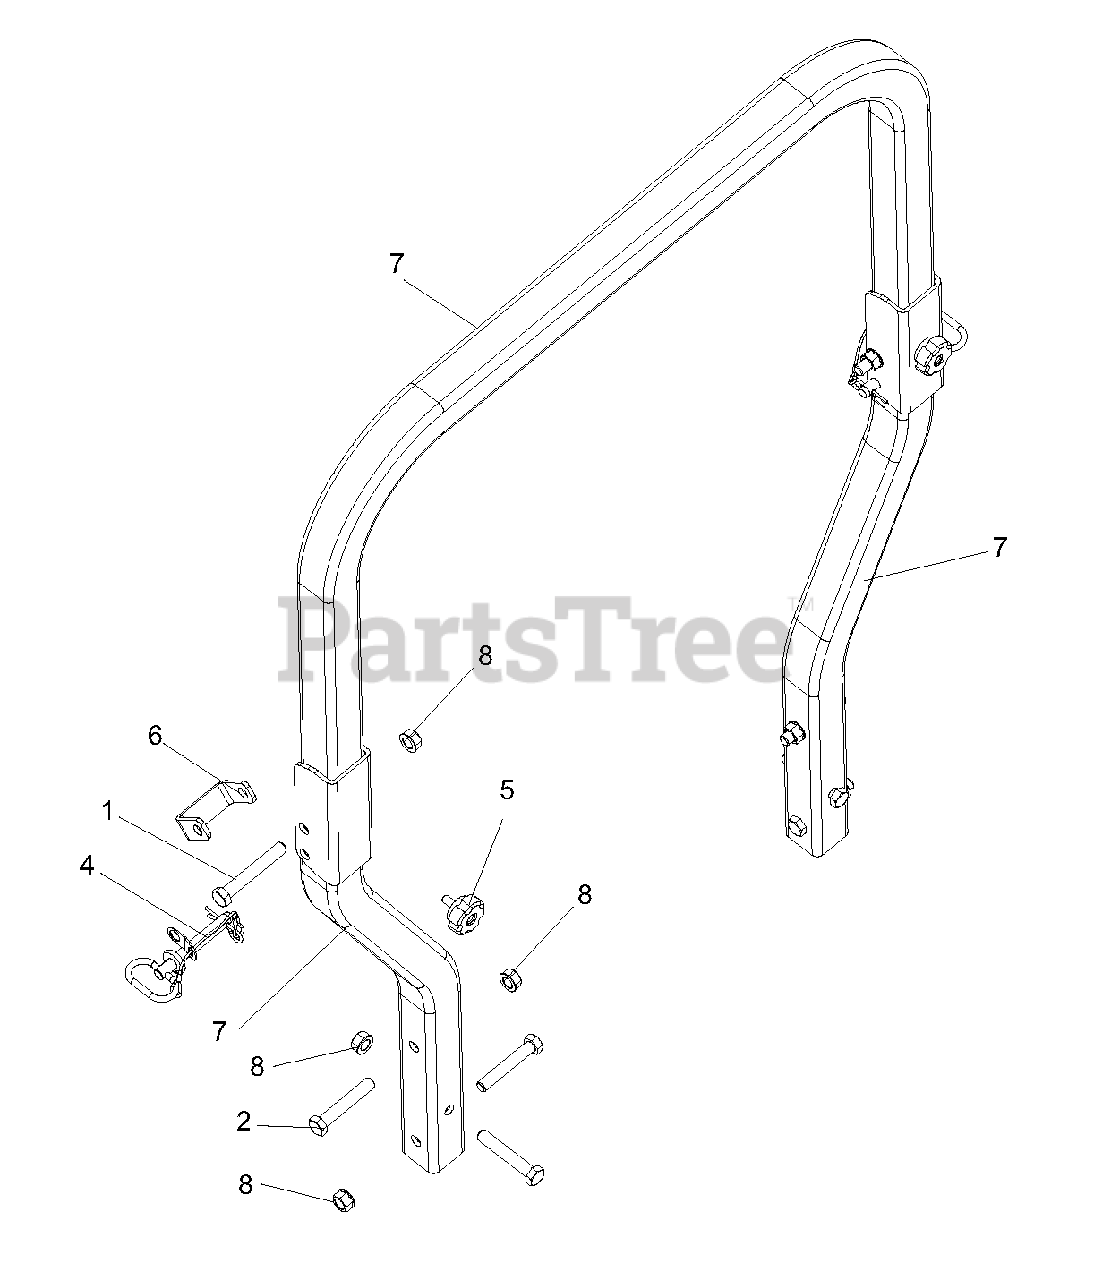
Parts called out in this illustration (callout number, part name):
1	BLT-HEX .50-13X3.50 GR5 YWZC
2	BLT-HEX .50-13X3.00 GR5 YWZC
4	ASSY, ROPS PIN/LANYARD
5	KNOB, ROUND 5/16-18 X .750
6	BRKT, ROPS STOP
7	ROPS, PRO-TURN 400 REPLACEMENT
8	NUT, LK-TOP-FLG .50-13 YWZC
